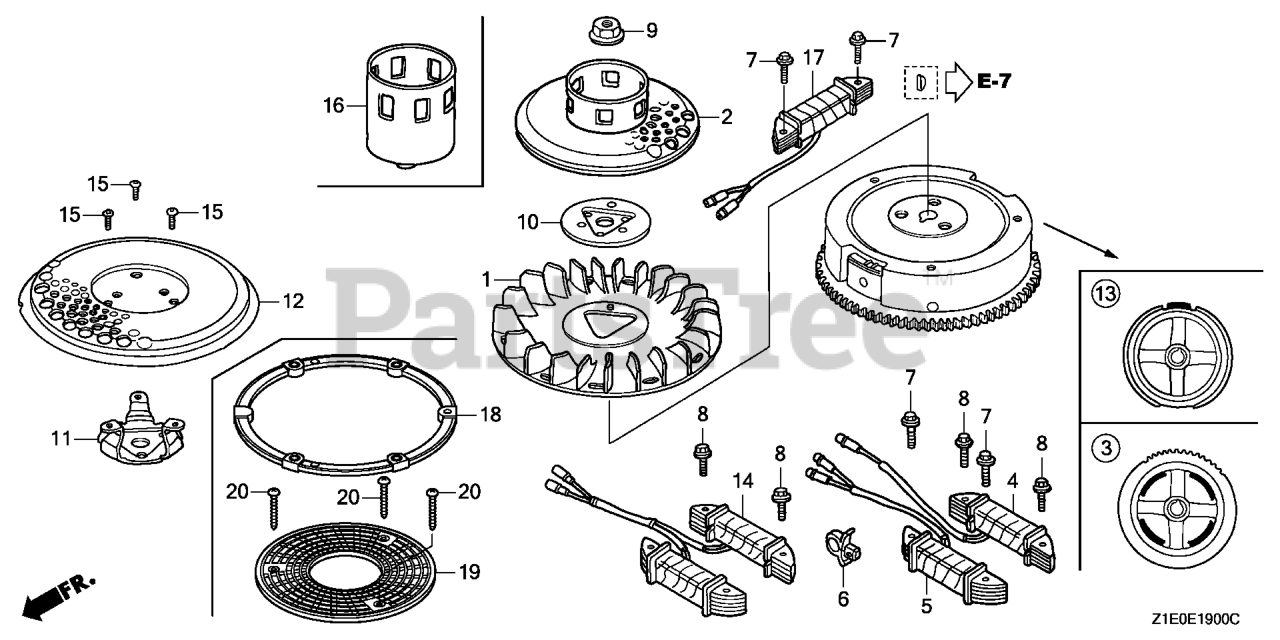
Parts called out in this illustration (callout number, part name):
1	FAN, COOLING
3	FLYWHEEL COMP. (SEL-4 POLE)
8	BOLT, FLANGE (6X32)
9	NUT, SPECIAL (16MM) (1)
10	PLATE, COOLING FAN SETTING
14	COIL ASSY., CHARGE (10A)
